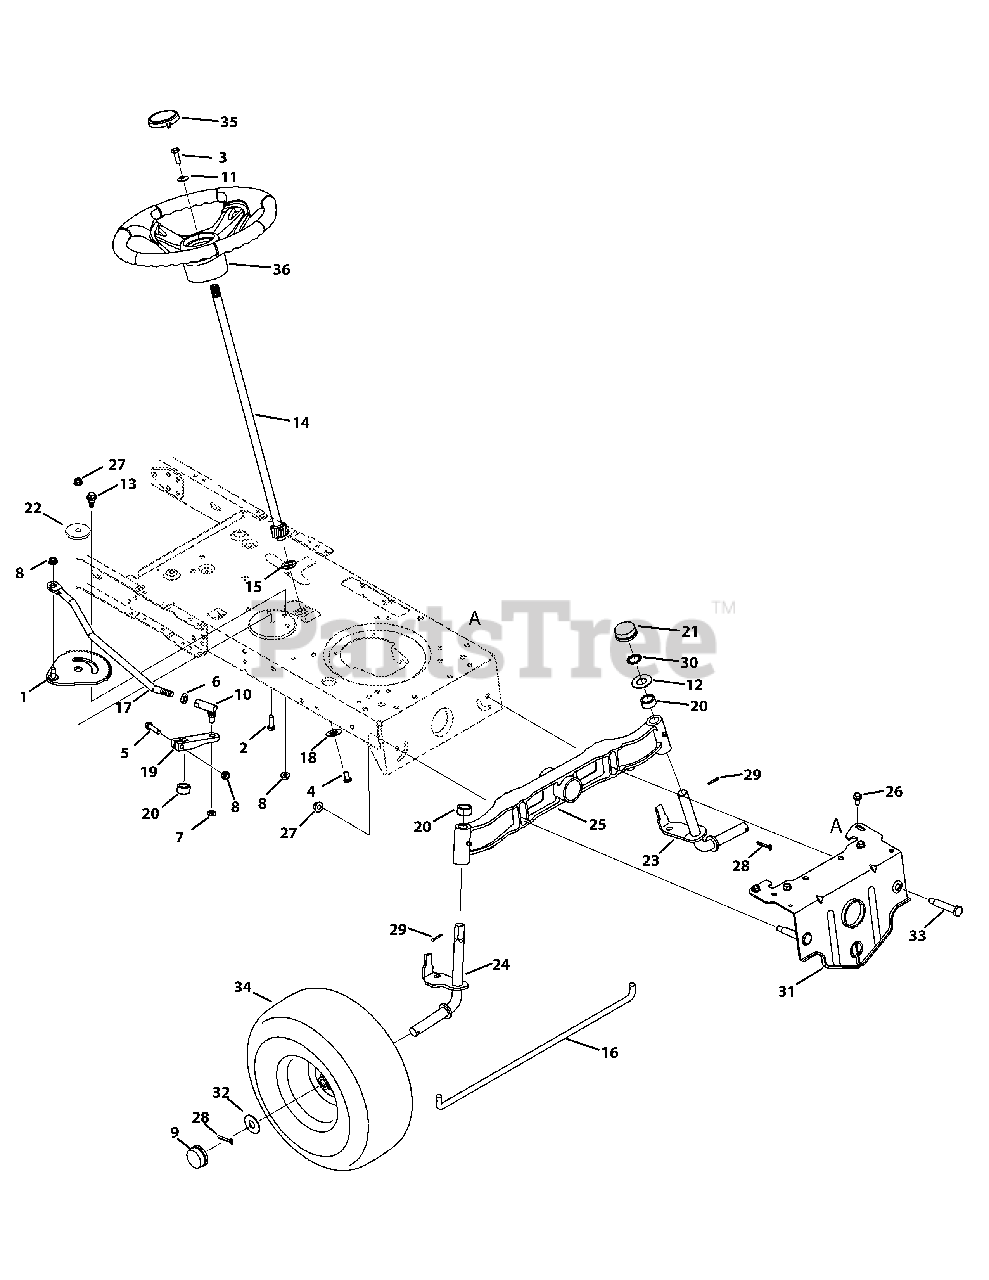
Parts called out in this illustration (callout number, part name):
1	Front Steering Gear Assembly
2	Hex Screw, 3/8-16 x 1.00
3	Screw, 5/16-18, 1.00, Gr5, Lock
4	Screw, Mach, 5/16-18, 0.750
5	Screw, 5/16-18, 1.75, Gr5
6	Nut, Jam, 7/16-20, Gr2
7	Nut, Hex Lock, 3/8-24
8	Nut, Flange Lock, 5/16-18, Grf
9	Hub Cap
10	Ball Joint, 7/16-20, Lock
11	Washer, Bell, .340 x .872 x .060
12	Washer, Flat, .78 x 1.59 x .60
13	Shoulder Screw, .435 x .3485, 5/16-18
14	Steering Shaft, 5/8 Spline x 21.86
15	Bearing, Flange, Hex 5/8
16	Tie Rod
17	Steering Link
18	Cap, 1.25 x .16
19	Steering, Block
20	Spacer, .710 ID x .125 OD x .56
21	Push Cap, Cast
22	Shoulder Spacer, .884 x .190
23	Axle Assmbly LH (38" & 42" Deck)
23	Axle Assembly, LH (46" Deck)
24	Axle Assmbly RH (38" & 42" Deck)
24	Axle Assembly, RH (46" Deck)
25	Pivot Bar, Cast
26	Screw, 5/16-18, 0.750
27	Nut, Flange Lock, 3/8-16, GrF
28	Pin, Cotter, 5/32, 1.25
29	Pin, Cotter, 1/8 x 0.75
30	Push Nut 3/4 Dia.
31	Pivot Bar Bracket
32	Washer, Flat, .781 x 1.59
33	Scr., Shlder, .500 x 2.380, 3/8-16
34	Wheel Ass’y, Sq. Shldr., 15 x 6 x 6.5
34	Wheel Ass’y, 15 x 6 x 6 - Grey
34	Wheel Ass’y, 15 x 6 x 6 - Yellow
35	Cap, Steering Wheel (Sprig Logo)
36	Steering Wheel, Standard Grip
